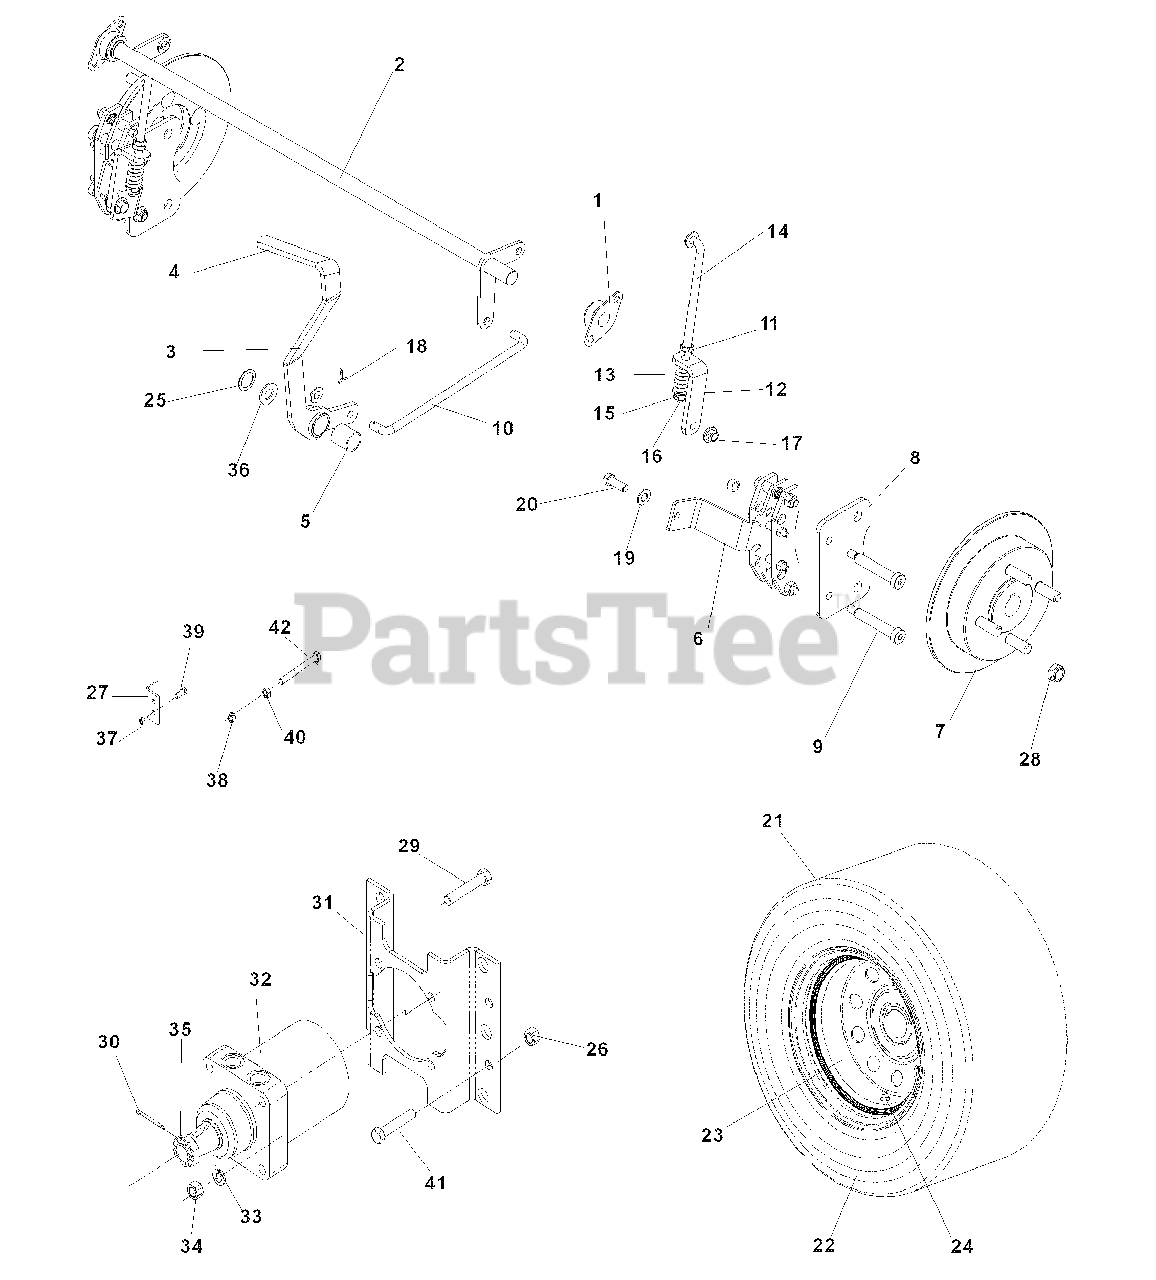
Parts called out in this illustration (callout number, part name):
2	BRAKE CROSS SHAFT
3	BRAKE LEVER
4	GRIP PARK BRAKE
6	CALIPER
8	PLATE, BRAKE
9	SCREW, 3/8 -16 x 2 1/2, SKT
10	LINKAGE, BRAKE
11	NUT, 3/8 -24, JAM
14	LINKAGE, REAR BRAKE
15	WASHER, 3/8, SAE
16	NUT, 3/8 -24, CENTERLOCK
17	NUT, 3/8 -16, THIN NYLOC
18	PIN COTTER, 3/32 x 3/4
19	WASHER, 3/8, SAE
20	HCS, 3/8 -16
21	TIRE, MODELS: 968999256,968999258, 968999307, 968999526, 968999527, 968999528
23	RIM, MODELS: MODELS: 968999254 968999255
24	VALVE STEM
25	RING, RETAINING, EXT 7/8
26	NUT, 1/2 -13, NYLOC
28	NUT, 1/2 -20, LUG
29	HCS, 1/2 -13 x 2 3/4
30	PIN COTTER
31	MOTOR STANDOFF
32	WHEEL MOTOR
33	LOCKWASHER, 1/2
34	NUT,1/2 -13
35	HEX SLOTTED NUT
37	NUT, 1/4 -20, NYLOC
38	NUT, 3/8 -16, NYLOC
39	HCS, 1/4 -20 x 3/4
40	NUT, 3/8 -16, WHIZLK
41	BOLT, 1/2 -13 x 1 1/4, WHIZLK
42	HCS, 3/8 -16 x 2 1/2
